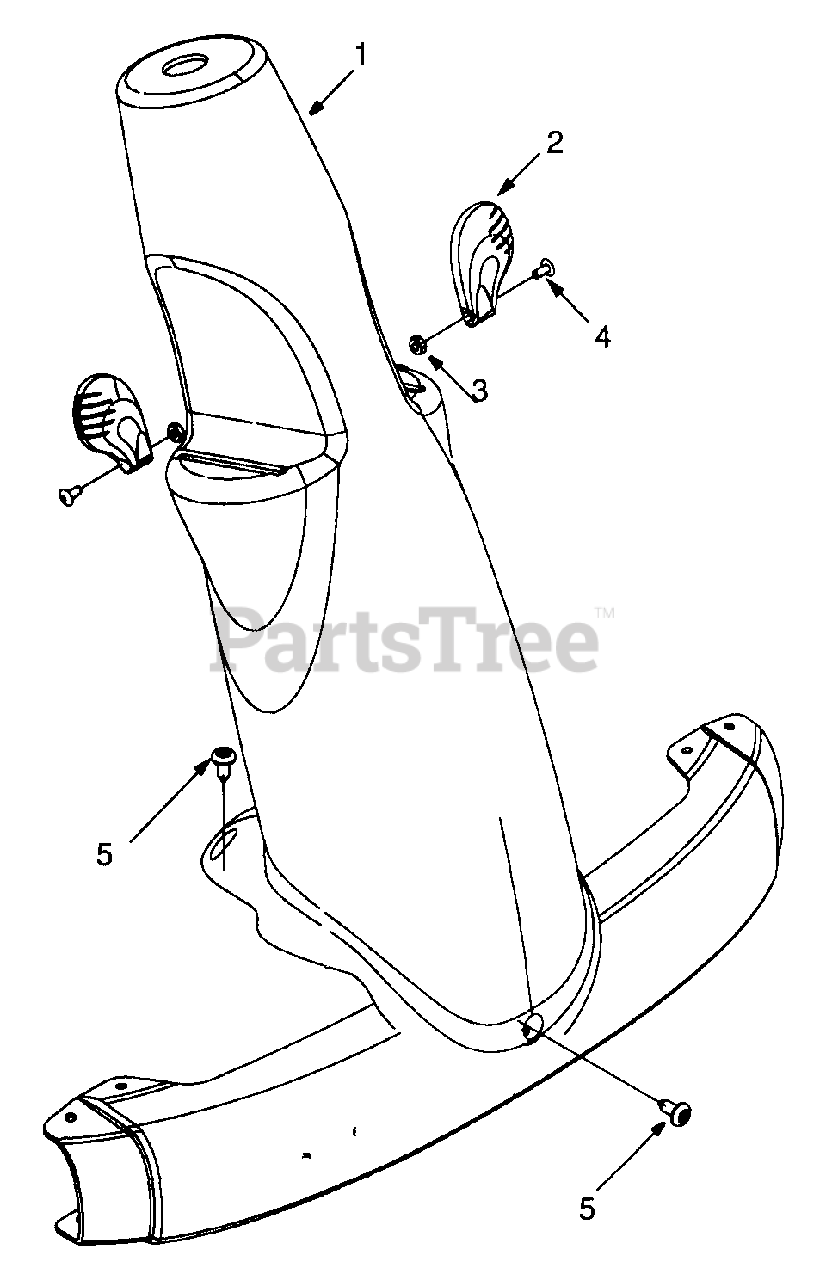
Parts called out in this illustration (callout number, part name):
1	Steering Column: Green
2	Control Knob: Yellow
3	Hex Nut 8-32
4	Pan Head Machine Screw #8-32
5	Torx Head AB Screw 1/4-14 x .625
